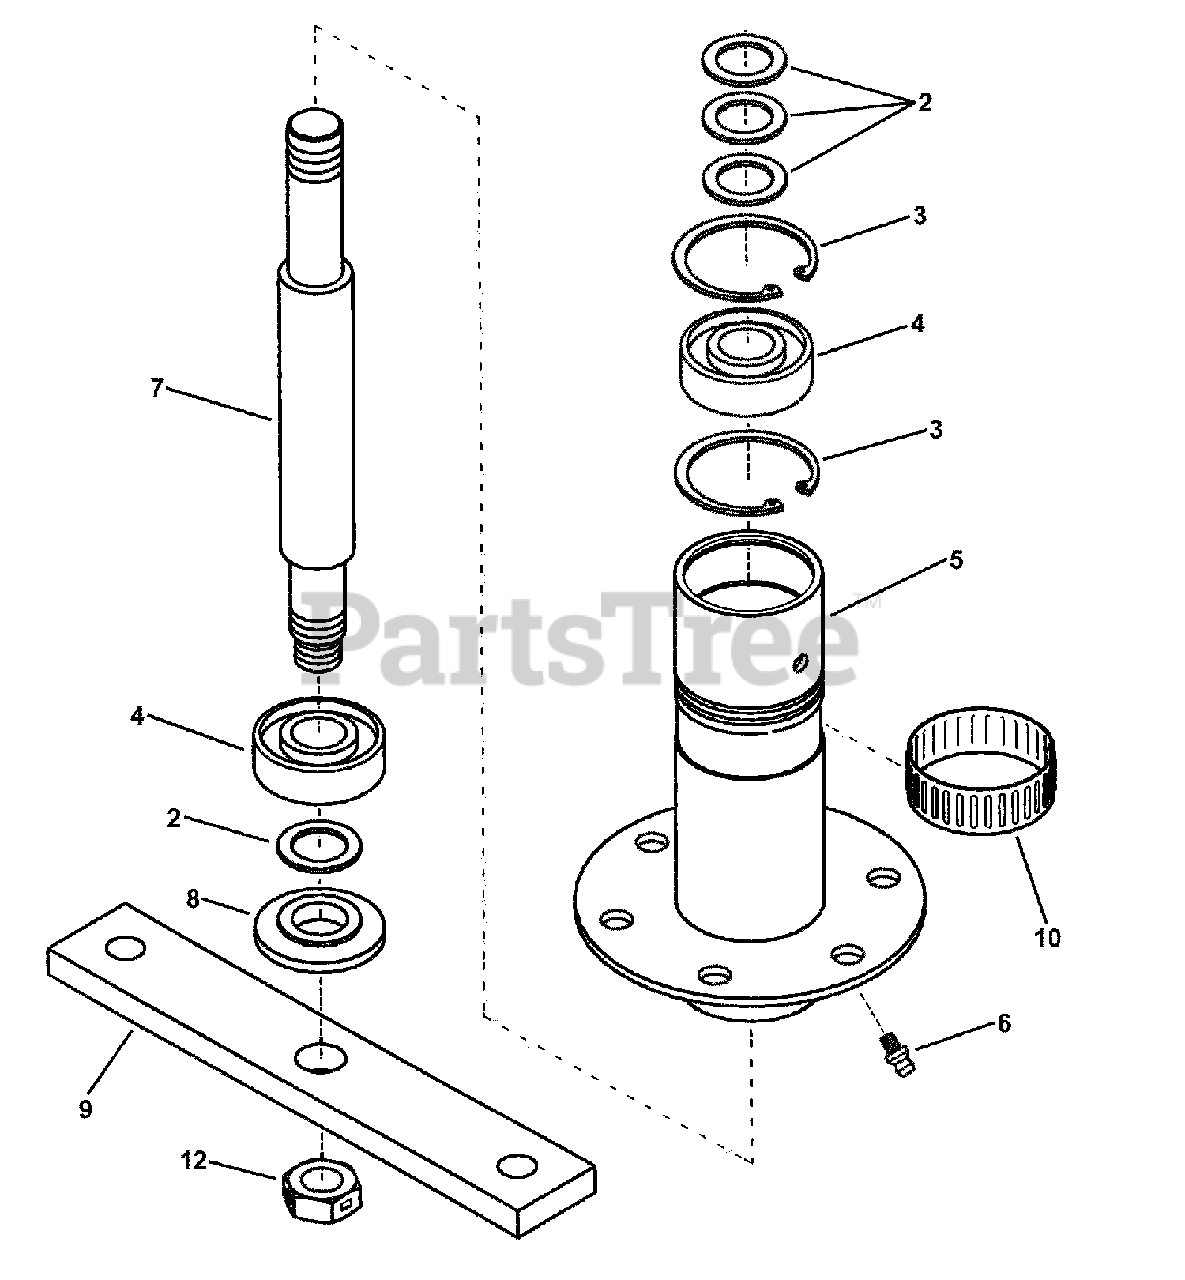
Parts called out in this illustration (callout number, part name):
1	ASSEMBLY, Spindle Housing
2	WASHER, 49/64" Shim
3	RING, 1-3/4" External Retaining
4	BEARING, Spindle
5	HOUSING,Spindle
6	FITTING, Lube (Press fit for .187 hole-no ball)
7	SPINDLE (8.96" long)
8	WASHER, Spindle
9	HOLDER, Blade
10	RING, Tolerance
12	NUT, 5/8-18 Hex Center Lock
